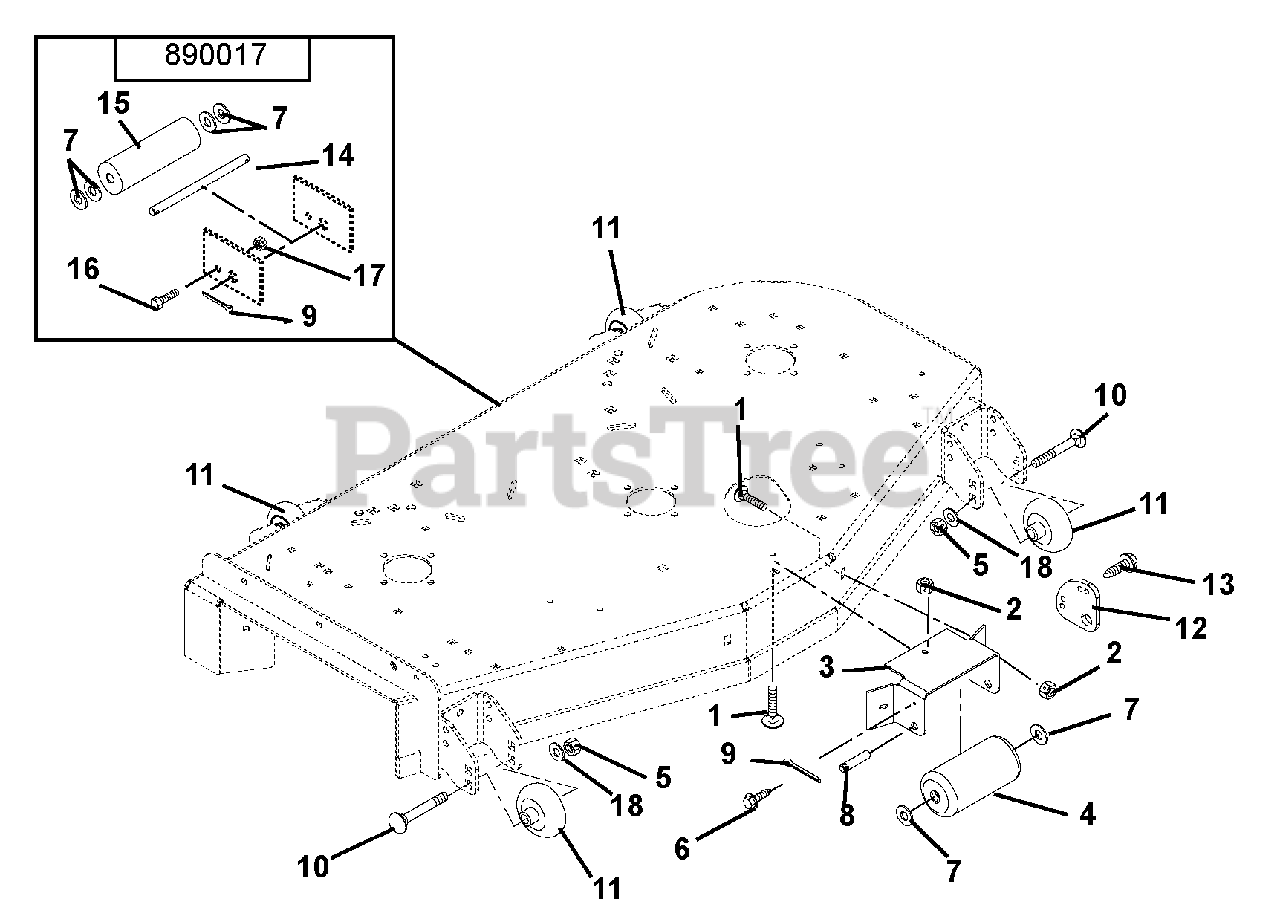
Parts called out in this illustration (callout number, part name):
1	Bolt-Round Head Square Neck .38-16 x 1.00 Grade 5
2	Nut-Locking-Top-Flange .38-16
3	Bracket- Anti-Scalp Roller
5	Nut-Locking-Nylon .50-13
6	Screw-Tapping .25-20 x .75 Hex Washer Head
7	Washer-Flat-Steel .656 x 1.31 x .095 (016)
9	Pin-Cotter .25 x 2.00 (016)
10	Bolt-Round Head Square Neck .50-13 x 5.00 Grade 2
11	Wheel, 3 x 5
12	Anti-Scalp Washer
13	Screw-Tapping .25-20 x .62 Hex Washer Head
14	Shift, Center Roller (017)
15	Roller, Gage (017)
16	Bolt-Hex .25-20 x .75 Grade 5 (017)
17	Nut-Locking-Center .25-20 (017)
18	Washer-Flat-Steel .531 x 1.06 x .095
